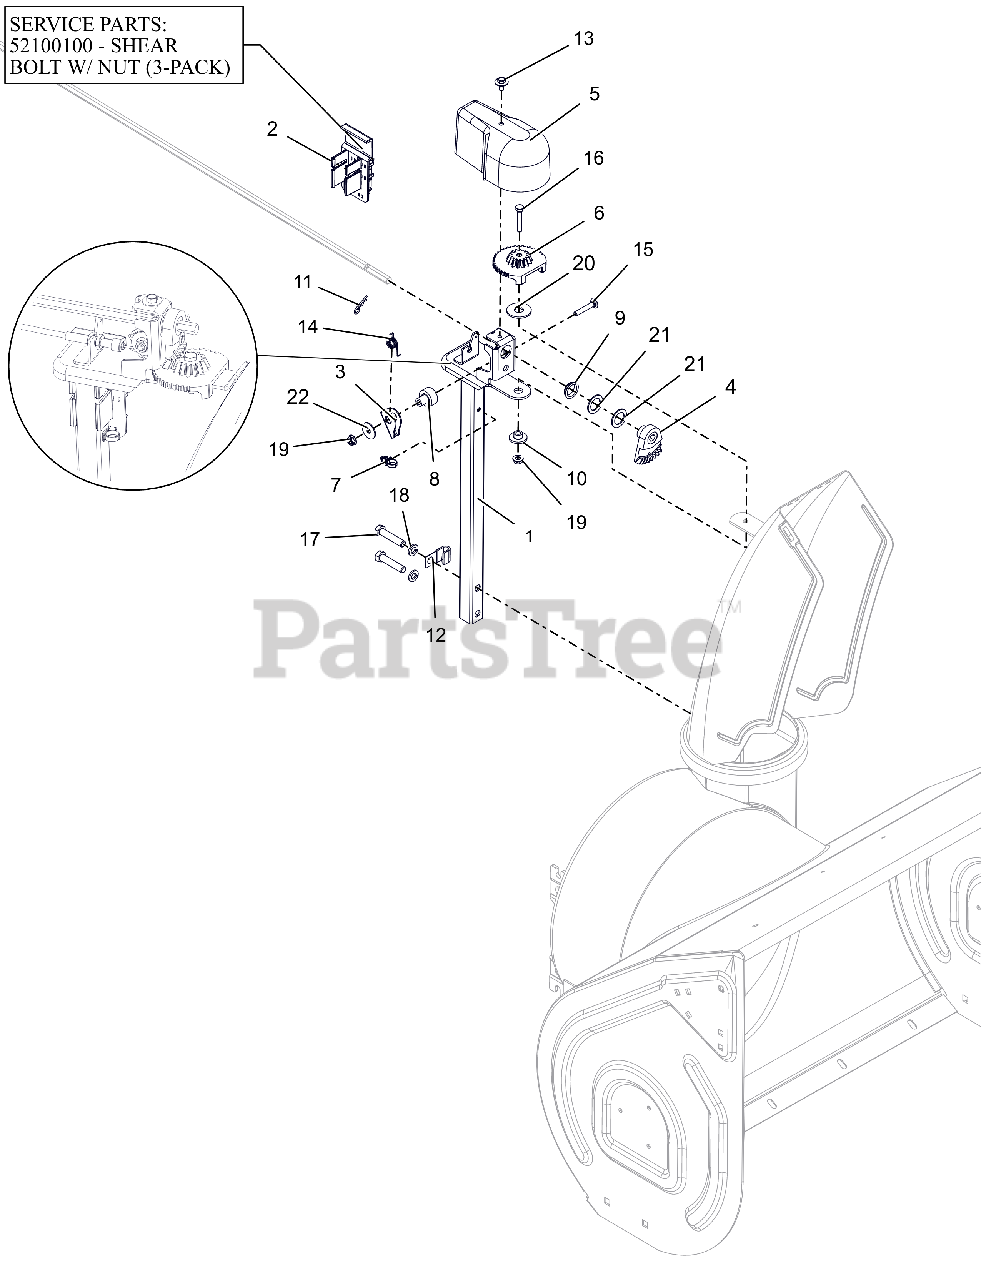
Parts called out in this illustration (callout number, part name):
1	PEDESTAL, CHUTE - QUICK STICK
2	HOLDER W LARGE SHEAR BOLT /NUT
2	SHEAR BOLT SERVICE ASSEMBLY
3	ARM, LOCKING
4	GEAR, CHUTE-ACTUATION
5	COVER, CHUTE GEAR
6	GEAR, CHUTE
7	CLIP, CABLE GUIDE
8	BUSHING, LOCK ARM
9	BUSHING, POLYLINER-.75 SNAPIN
10	BSHG-FLG .265X.477X.375X1.00
11	PIN-HAIR INT .08X.18X1.18 YWZC
12	J-CLAMP
13	SCR-TAP .25-20X.50 LGHWH TR YZ
14	SG-TORS
15	@BLT-RDHDSQNK .25-20X1.50 G5YZ
16	@BLT-HEX .25-20X1.50 GR5 YWZC
17	@BLT-HEX .38-16X1.75 GR5 YWZC
18	@WSHR-LK .38X.094 REG YWZC
19	@NUT-LK-CTR-FLG .25-20 YWZC
20	WSHR-FLT-NYL .515X1.375X.093
21	WSHR-FL-STL.754X1.125X.062YWZC
22	WSHR-FL-STL .281X1.000X.063
